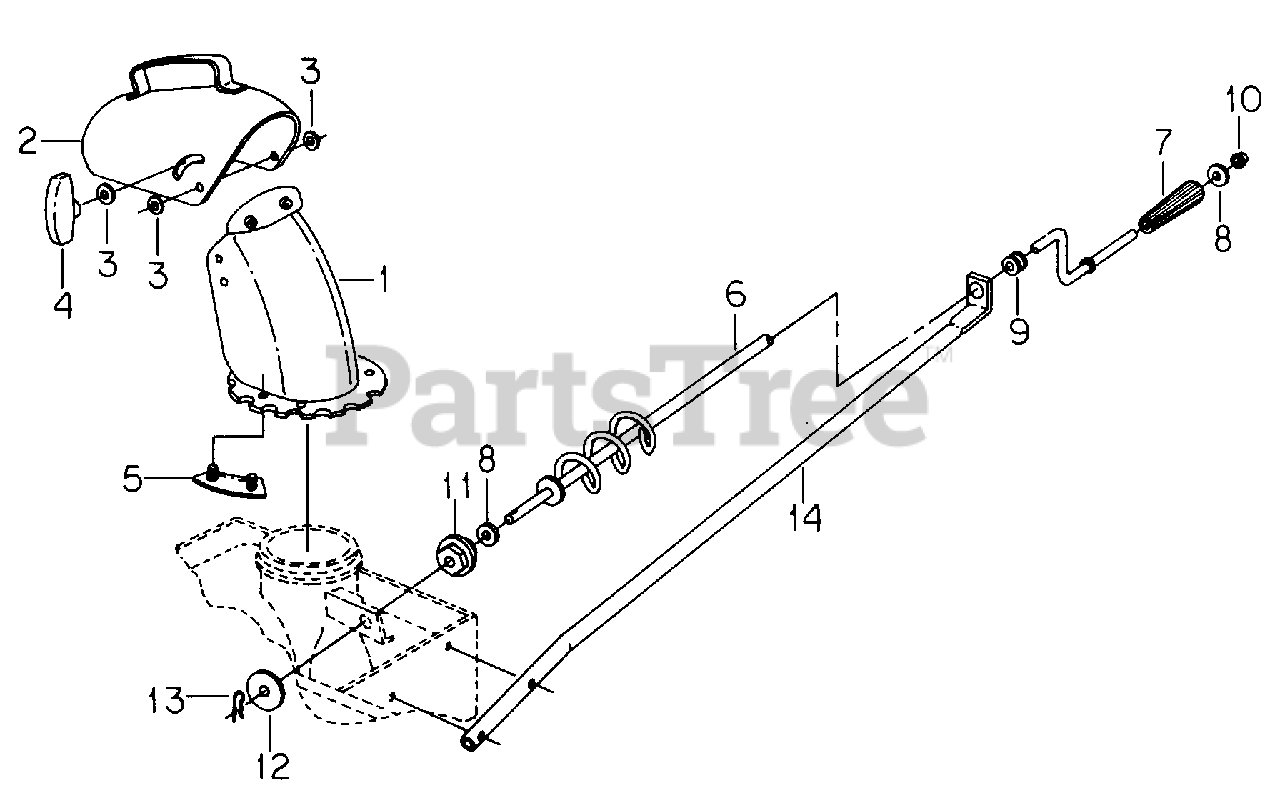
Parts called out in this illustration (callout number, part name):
2	Deflector w/Product Graphic, Chute
3	Washer, .34 X .88 X .60 Belleville
4	Knob, Deflector Adjusting
5	Retainer, Chute
6	Crank, Chute
7	Knob, Chute Crank
8	Washer, .406 X .734 X .056
9	Grommet, Chute Crank
11	Bushing, Chute Crank
12	Washer, .406 X 1.500 X .054
13	Pin, 3/32 X 3/4 Pln Cot
14	Support, Chute Crank
